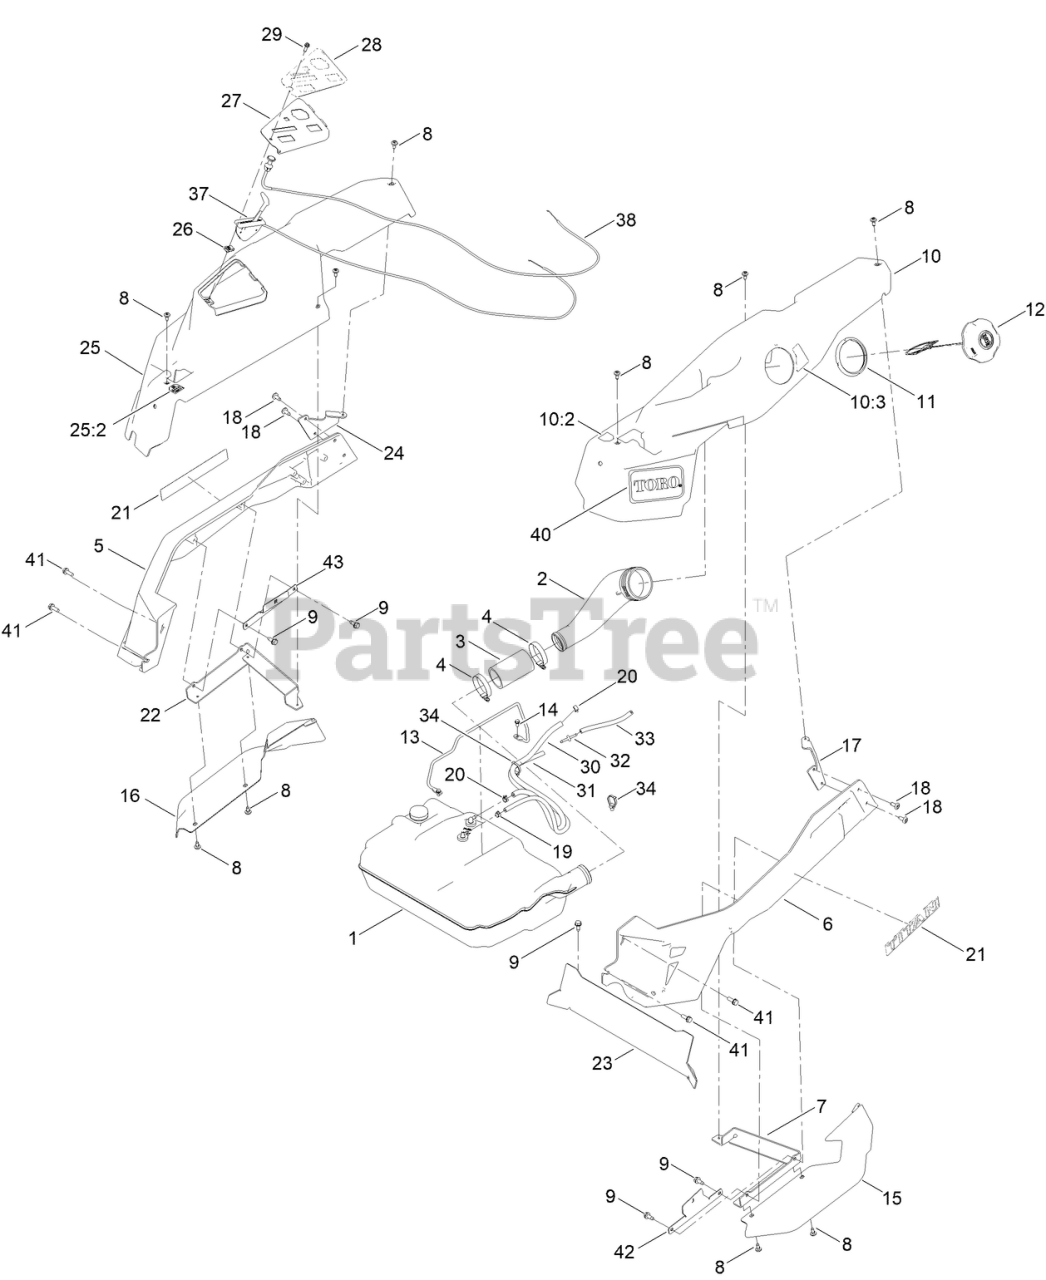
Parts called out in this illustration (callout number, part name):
1	TANK ASM - FUEL
2	NECK-FILLER, FUEL
3	HOSE-FILLER, FUEL
4	CLAMP-HOSE
5	CAST-TUBE, RH [RED]
6	CAST-TUBE, LH [RED]
7	MOUNT-POD BRACKET LH
8	SCREW-SHOULDER
9	SCREW-HWHTF
10	POD ASM - LH W/DECALS
10:2	DECAL-CONTROL LEVER, LH
10:3	DECAL-FUEL FILL
11	RING-RETAINING
12	CAP-FUEL, RATCHETING
13	ROD-HOLD DOWN
14	SCREW-HWH
15	FENDER-TIME CUTTER, LH
16	FENDER-TIME CUTTER, RH
17	BRACKET-REAR POD, LH
19	CLAMP-HOSE
20	CLAMP-HOSE
21	DECAL-TITAN
22	MOUNT-POD BRACKET RH
23	PLATE-KICK
24	MOUNT-POD BRACKET RH
25	POD ASM - RH W/DECALS
25:2	DECAL-CONTROL LEVER, RH
27	PANEL-CONTROL
28	DECAL - CONTROL PANEL
29	SCREW-HWHTF
30	HOSE-FUEL
31	HOSE-FUEL
32	ADAPTER ORIFICE
33	HOSE-FUEL
34	CLIP-TIE
37	CABLE-THROTTLE
38	CABLE-CHOKE
40	DECAL - TORO LOGO
41	SCREW-TAPTITE
42	BRACKET-ALIGNMENT, POD LH
43	BRACKET- ALIGNMENT, POD RH
